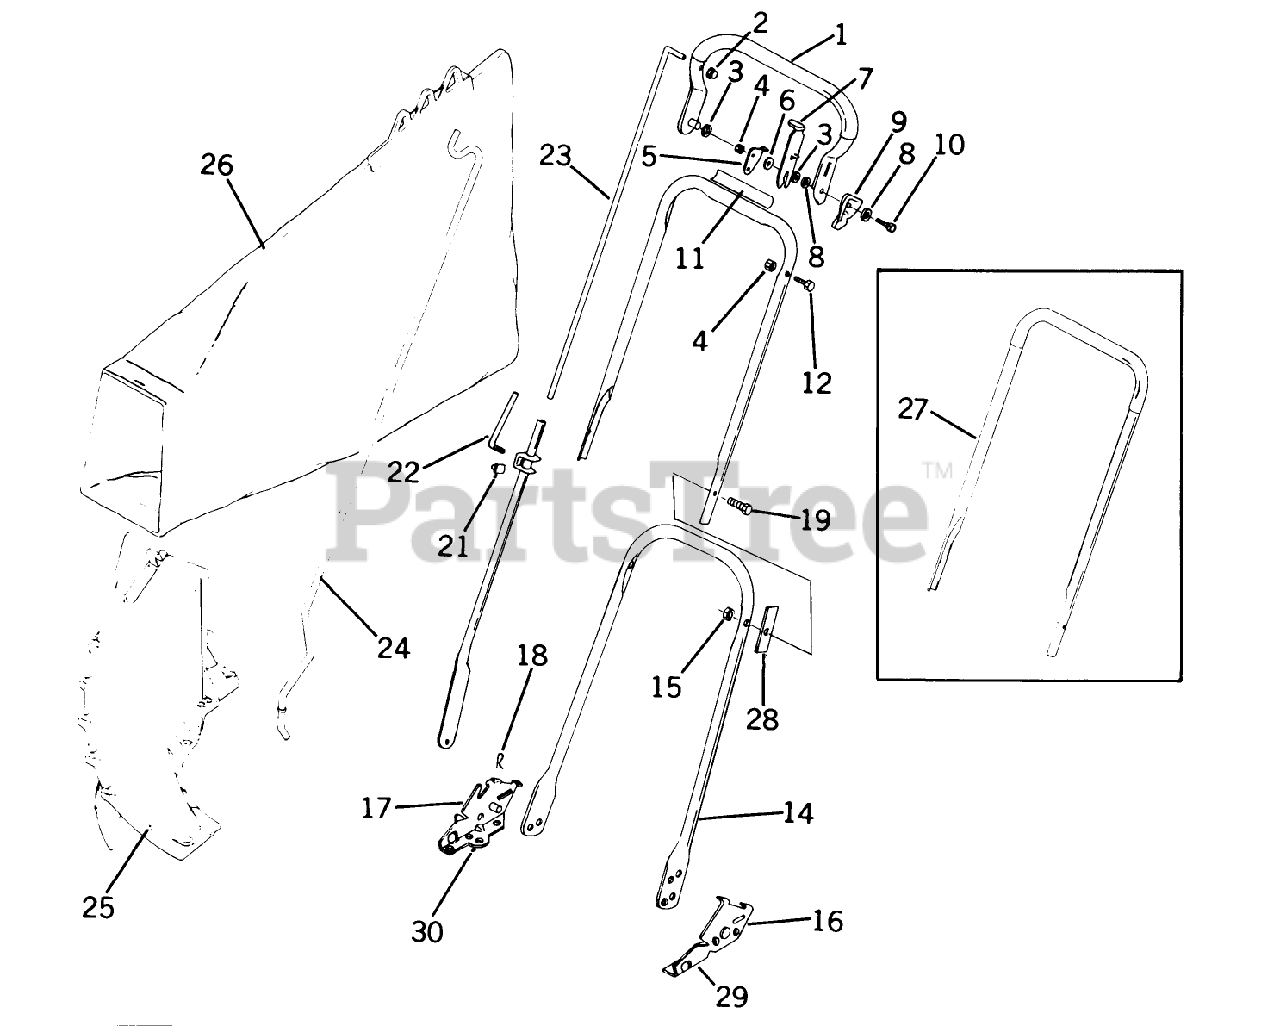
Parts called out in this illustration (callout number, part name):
3	WASHER M
4	LOCKNUT E
5	HANDLE STOP
6	WASHER
7	LEVER LOCKOUT
10	BOLT PIONEER
12	SCREW-HANDLE STOP
15	LOCKNUT E
17	HANDLE BRACKET
18	HAIR PIN
19	SCREW - USE 137-3042
23	ROD CONTROL
24	ROD GRASSBAG
25	Chute Assembly
26	89802 LB WHOLE GOODS
